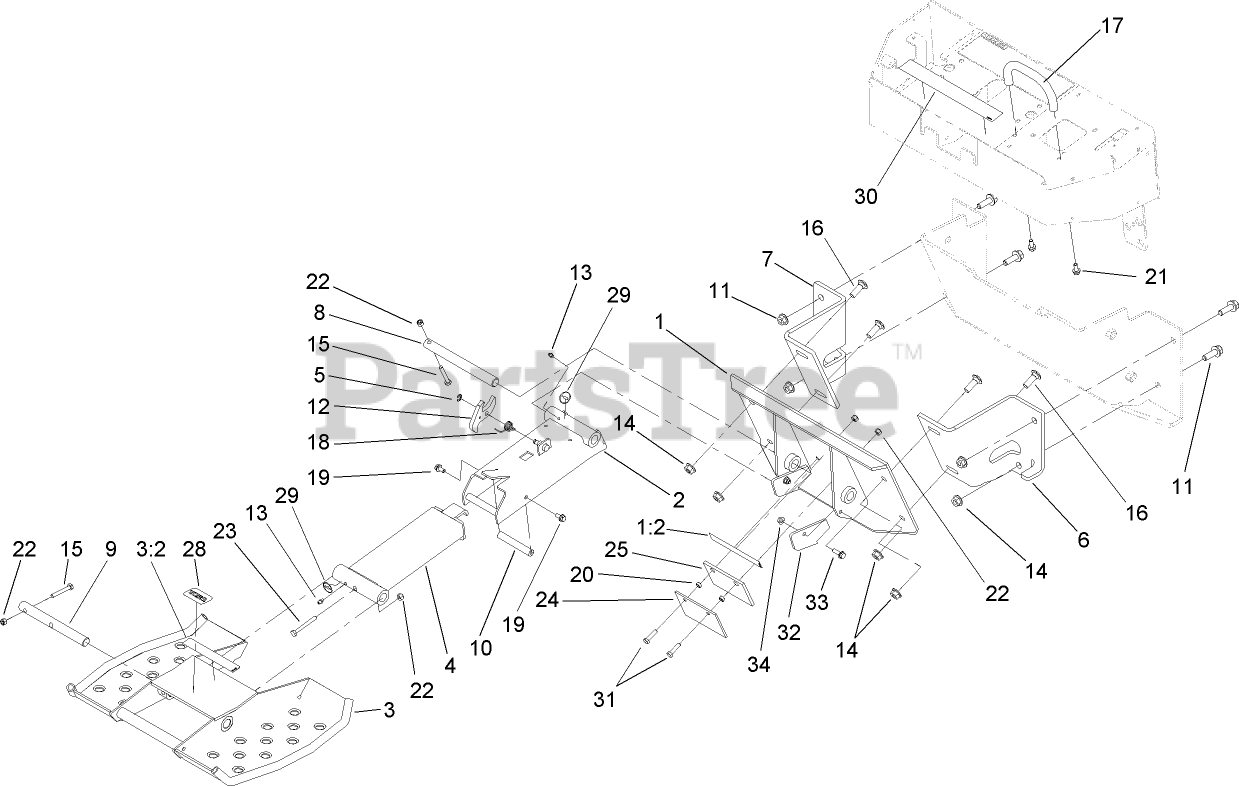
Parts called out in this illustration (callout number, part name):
1	MOUNTING PLATE ASM
1:2	DECAL-POINT, PINCH
2	LINKAGE-WRAPPER
3	PLATFORM ASM
3:2	DECAL-POINT, PINCH
4	SLIDE ASM
5	E-RING
6	PLATE-MOUNTING, RH
7	PLATE-MOUNTING, LH
8	PIN-UPPER
9	PIN-LOWER
10	ROD-CLAMP
11	SCREW-HHF
12	LATCH
13	FITTING-GREASE
14	NUT-HHF
15	SCREW-HH
16	SCREW-CARR
17	BAR-REFERENCE
18	SPRING-TORSION, RH
19	SCREW-HHF
20	SPACER
21	SCREW-HHF
22	NUT-LOCK, NI
23	SCREW-HH
24	PLATE-PUSH
25	PAD-RUBBER
28	Decal
29	DECAL-GREASE
30	DECAL-WARNING/INSTRUCTIONAL
31	SCREW-HH
32	PLATE-BUMPER
33	SCREW-HHF
34	NUT-HF
